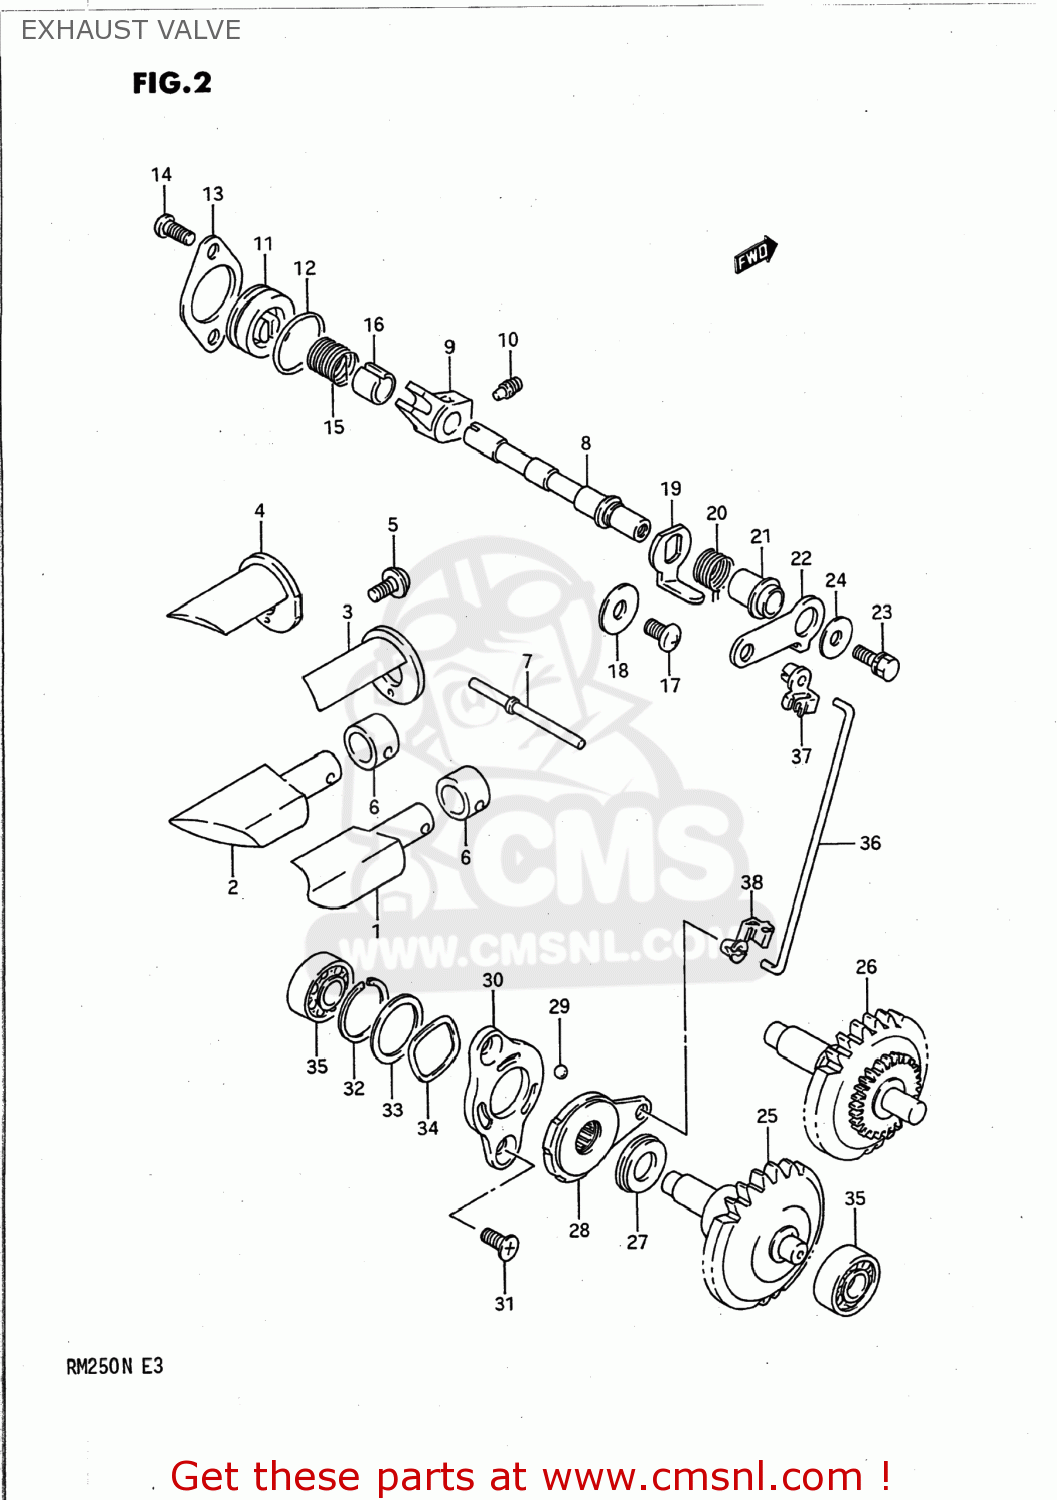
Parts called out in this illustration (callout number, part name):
1	VALVE,EXHAUST,R
2	VALVE,EXHAUST,L
3	GUIDE,EXHAUST VALVE,R
4	GUIDE,EXHAUST VALVE,L
5	SCREW
6	HOLDER,EXHAUST VALVE
7	PIN,EXHAUST VALVE 48.5MM
8	SHAFT,EXHAUST VALVE
9	ARM,EXHAUST VALVE SHAFT
10	SCREW
11	CAP,EXHAUST VALVE
12	O RING(D:1.9,ID:22.6)
13	RETAINER,EXHAUST VALVE
14	SCREW
15	SPRING
16	SPACER,EXHAUST VALVE SPRING
17	BOLT
18	WASHER
19	LEVER,EXHAUST VALVE NO
20	SPRING
21	SPACER,EXHAUST VALVE
22	LEVER,EXHAUST VALVE NO
23	BOLT
24	WASHER (5.5X16X1.2)
25	GOVERNOR ASSEMBLY,EXHAUST
26	GOVERNOR ASSY,EXHAUST VALVE
27	BEARING(10X22X2.8)
28	ACTUATOR,EXHAUST VALVE
29	BALL
30	STARTER,EXHAUST VALVE ACTUATOR
31	SCREW(5X10)
32	CIRCLIP
33	SHIM(19.1X25X0.3)
34	WASHER
35	BEARING(8X22X7)
36	ROD,EXHAUST VALVE
37	BUSH,EXHAUST VALVE ROD NO.1
38	BUSH,EXHAUST VALVE ROD NO.2
